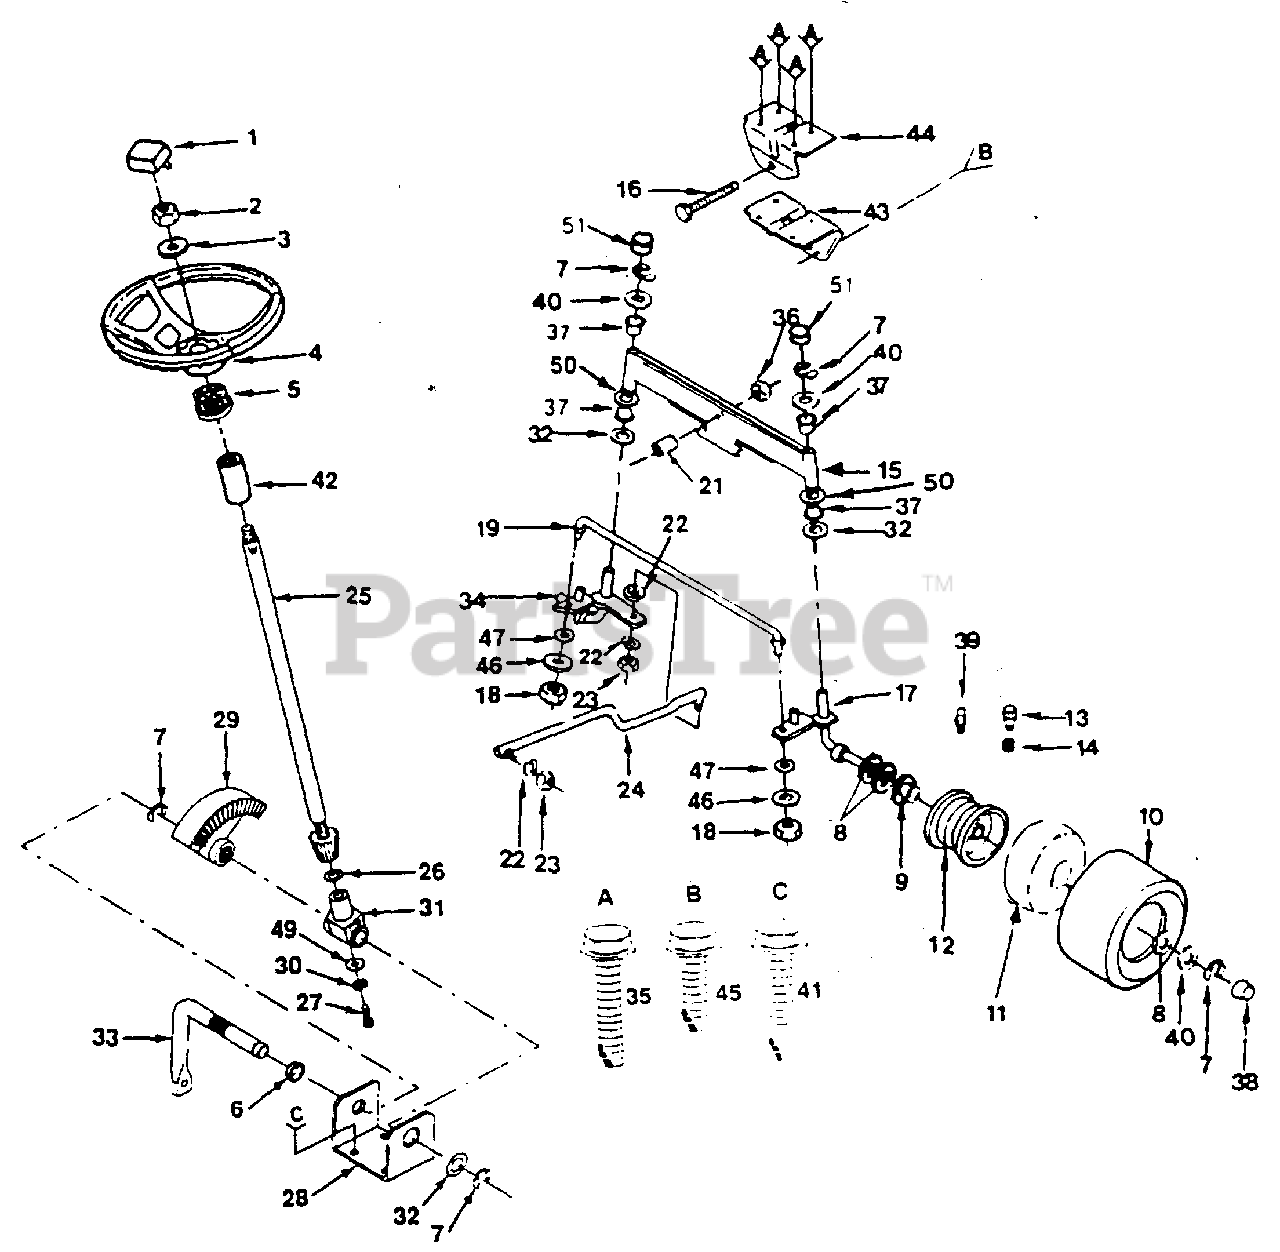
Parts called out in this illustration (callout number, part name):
1	Insert, Steering Wheel
2	Nut, Hex, Jam, Toplock 1/2-20
3	Washer 17/32 x 2-1/4 x .160
4	Steering Wheel
5	Adapter, Steering Wheel
6	Nyliner, Snap-in
8	Washer 25/32 x 1-1/4 x 16 Ga.
9	Bearings, Wheel, Front
10	Tire 15 x .00-6
11	Tube (Not furnished w/Tractor)
12	Rim Assembly, Front, (Includes 2 each Key No. 9)
15	Axle Assembly, Front
16	Bolt, Hex 5/8-11 x 3-3/4
17	Spindle Assembly, R.H.
18	Nut, Hex 5/16-24
19	Rod, Tie
21	Spacer, Bearing, Axle, Front
22	Washer, Lock 3/8
23	Nut, Hex 3/8-24
25	Shaft, Steering
27	Screw, Hex, Socket 1/4-20 x 5/8
28	Bracket, Assembly, Steering
29	Gear, Sector
30	Washer, Lock 1/4
31	Support, Shaft
32	Bearing, Thrust
33	Shaft, Pitman
34	Spindle Assembly, L.H.
35	Screw, Hex, Special
36	Locknut, Hex w Washer 5 8-16
37	Bearing
39	Fitting, Grease
40	Washer 25/32 x 1-5/8 x 16 Ga.
41	Screw, Hex, Washer Hd., Thd. Form. 3/8-16 x 3/4
42	Tube, Shaft, Steering
43	Support, Saddle, Front
44	Support, Saddle, Rear
45	Screw, Hex, Washer Hd., Thd. Roll. 5/16-18 x 1/2
46	Washer, Lock 5/16
47	Washer, 11/32 x 3/4 x 16 Ga.
49	Washer, Shim 1/4 x 5/8 x .062
50	Washer 27/32 x 1-1/4 x 16 Ga.
